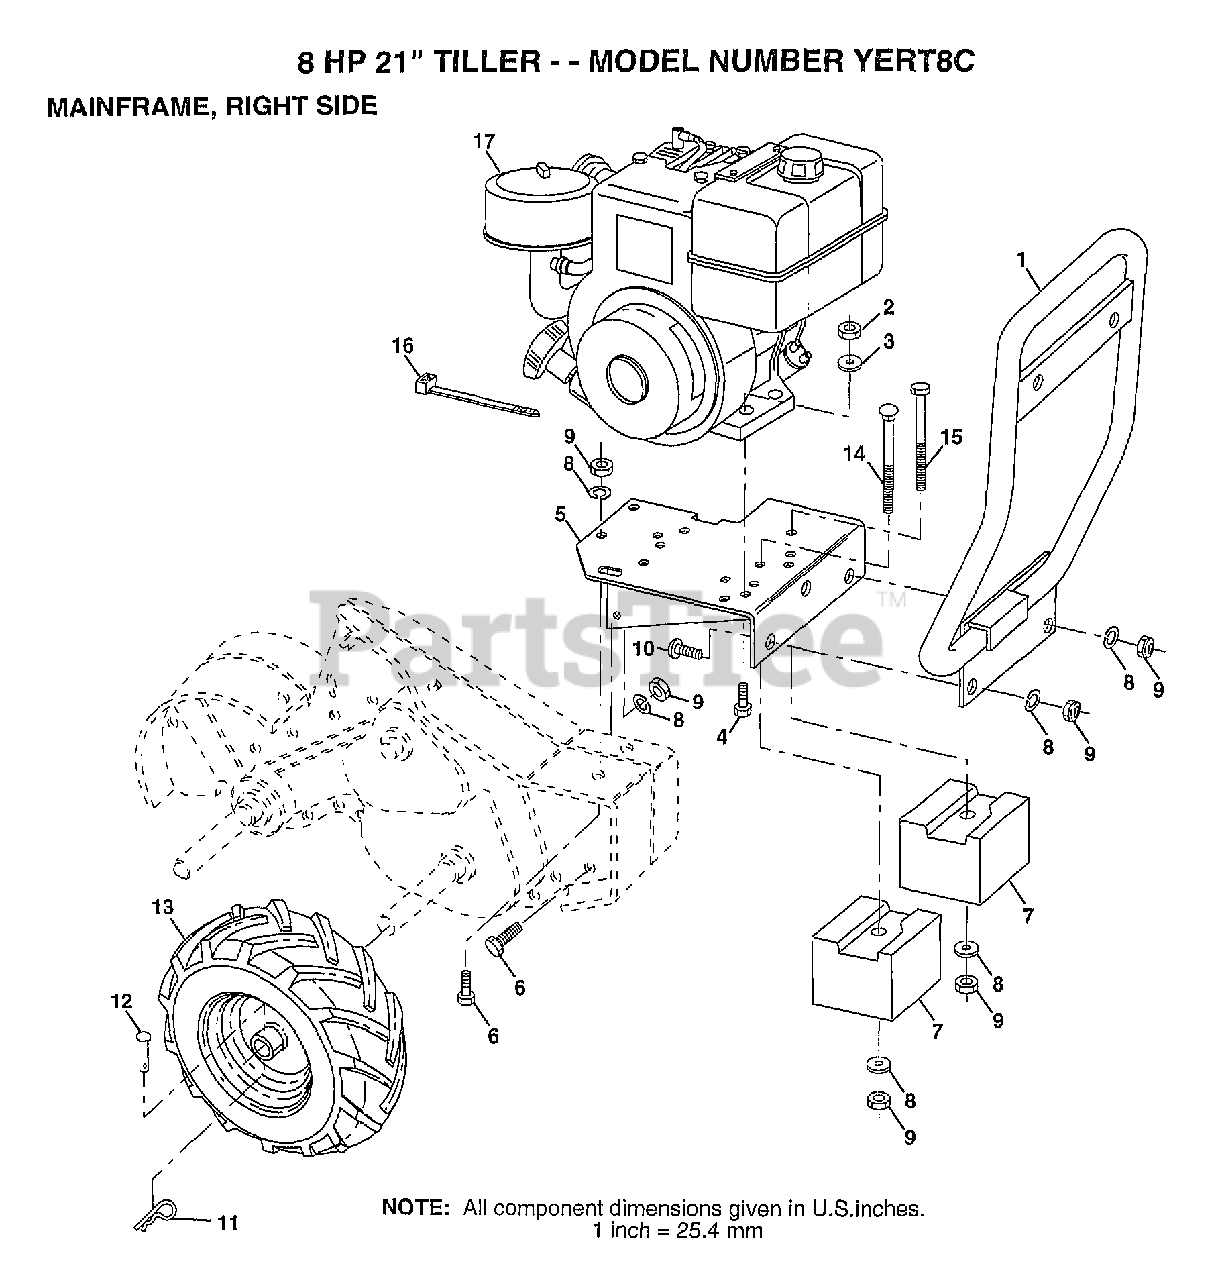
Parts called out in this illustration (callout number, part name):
1	BUMPER.ASM
2	NUT.HEX.5/16-18
3	LOCKWASHER
4	BOLT
5	"ASM. ENGINE, BASE"
6	BOLT
7	COUNTERWEIGHT CRT
8	LOCKWASHER
9	NUT.HEX.3/8-16UNC
11	SPRING.RETAINER
12	RIVET.PAN HD.1.75
13	TIRE TI
13	WHEEL TI
14	BOLT CRT
15	BOLT.3/8-16X4.5
16	TIE CABLE CRT
